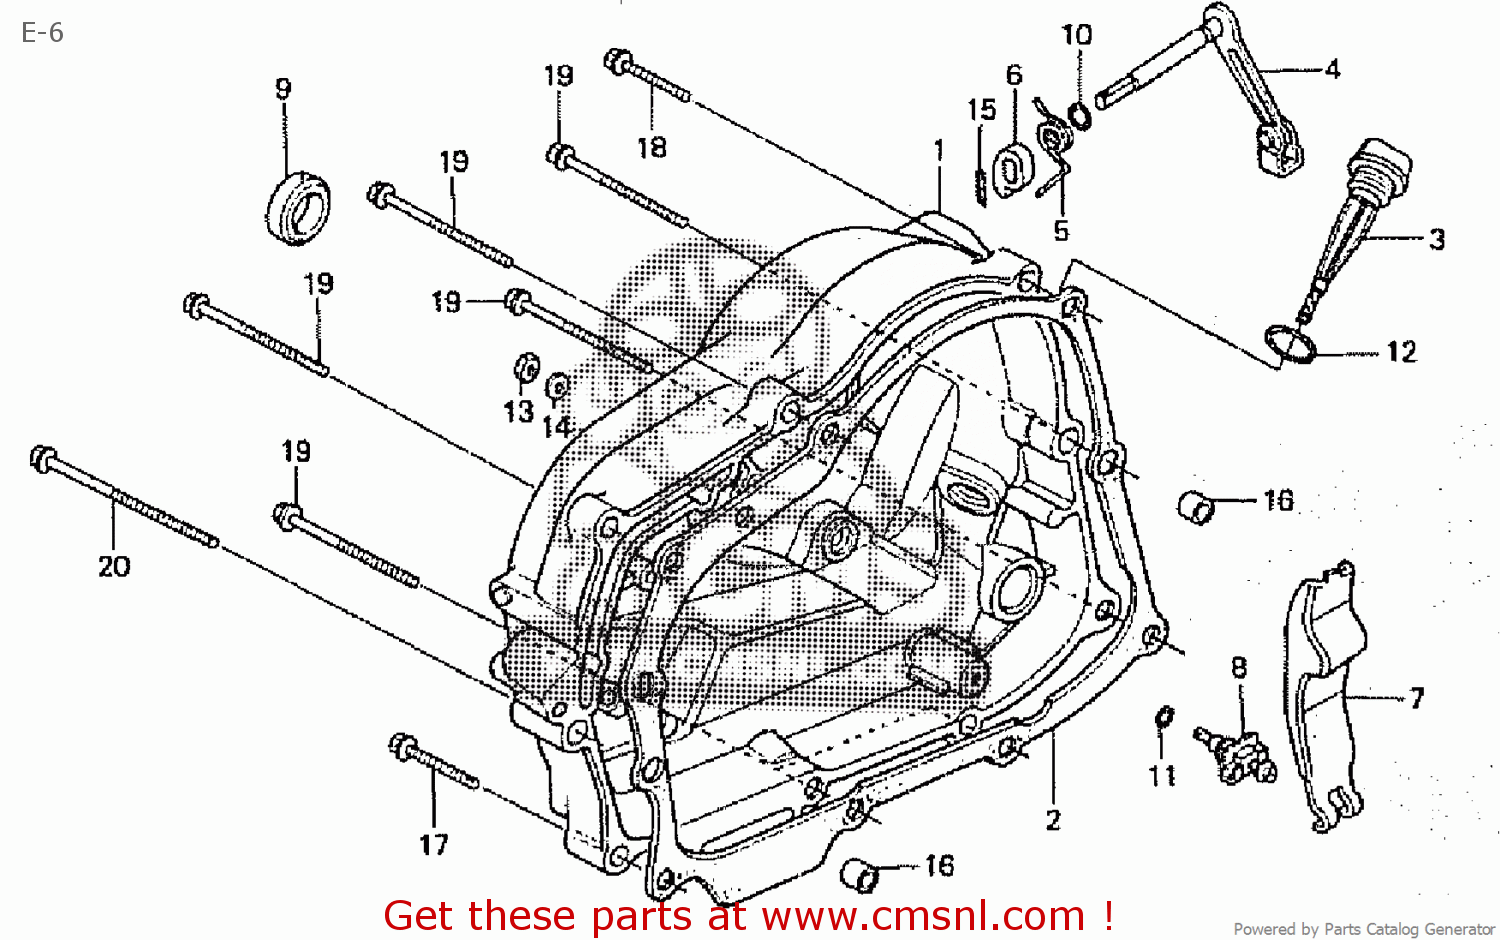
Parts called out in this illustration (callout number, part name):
2	GASKET,R.CRANKCAS (NAS)
3	GAUGE,OIL LEVEL
4	LEVER COMP,CLUTCH
5	SPG.,CLUTCH LEVER
6	CAM,CLUTCH LIFTER
7	LEVER,CLUTCH
8	SCREW,CLUTCH ADJ
9	OIL SEAL,18X29X7
10	ORING,6.8X1.9
11	O RING, 6M/M
12	ORING 183
13	NUT,HEX 6MM
14	WASHER,PLAIN, 6MM
15	PIN,COTTER 2.0X15
17	BOLT,FLANGE,6X35
18	BOLT,FLANGE,SH,6X40
19	BOLT,FLANGE,6X80
20	BOLT,FLANGE,6X100
